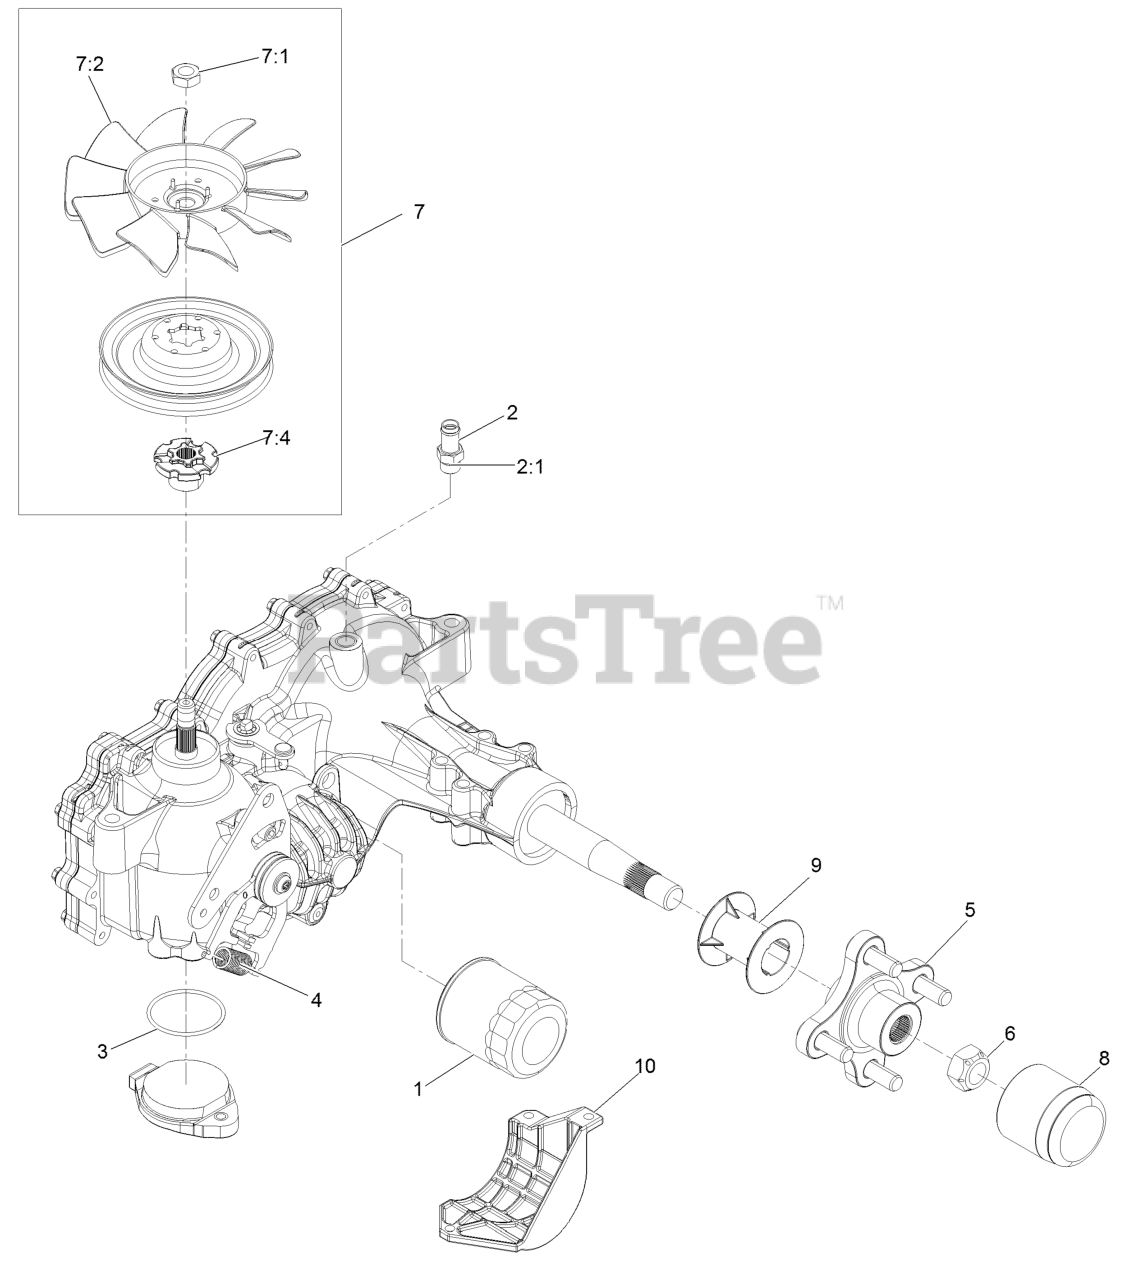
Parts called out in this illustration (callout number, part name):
1	ELEMENT-OIL FILTER, HYD
2	ADAPTER-STRAIGHT
2:1	O-RING
3	O RING-SEAL
4	SPRING-EXTENSION
5	HUB-OFFSET
6	NUT-HUB
7	FAN AND PULLEY KIT
7:4	HUB-PULLEY
8	CAP-AXLE, LONG
9	TUBE-AXLE
10	GUARD-FILTER, LH
